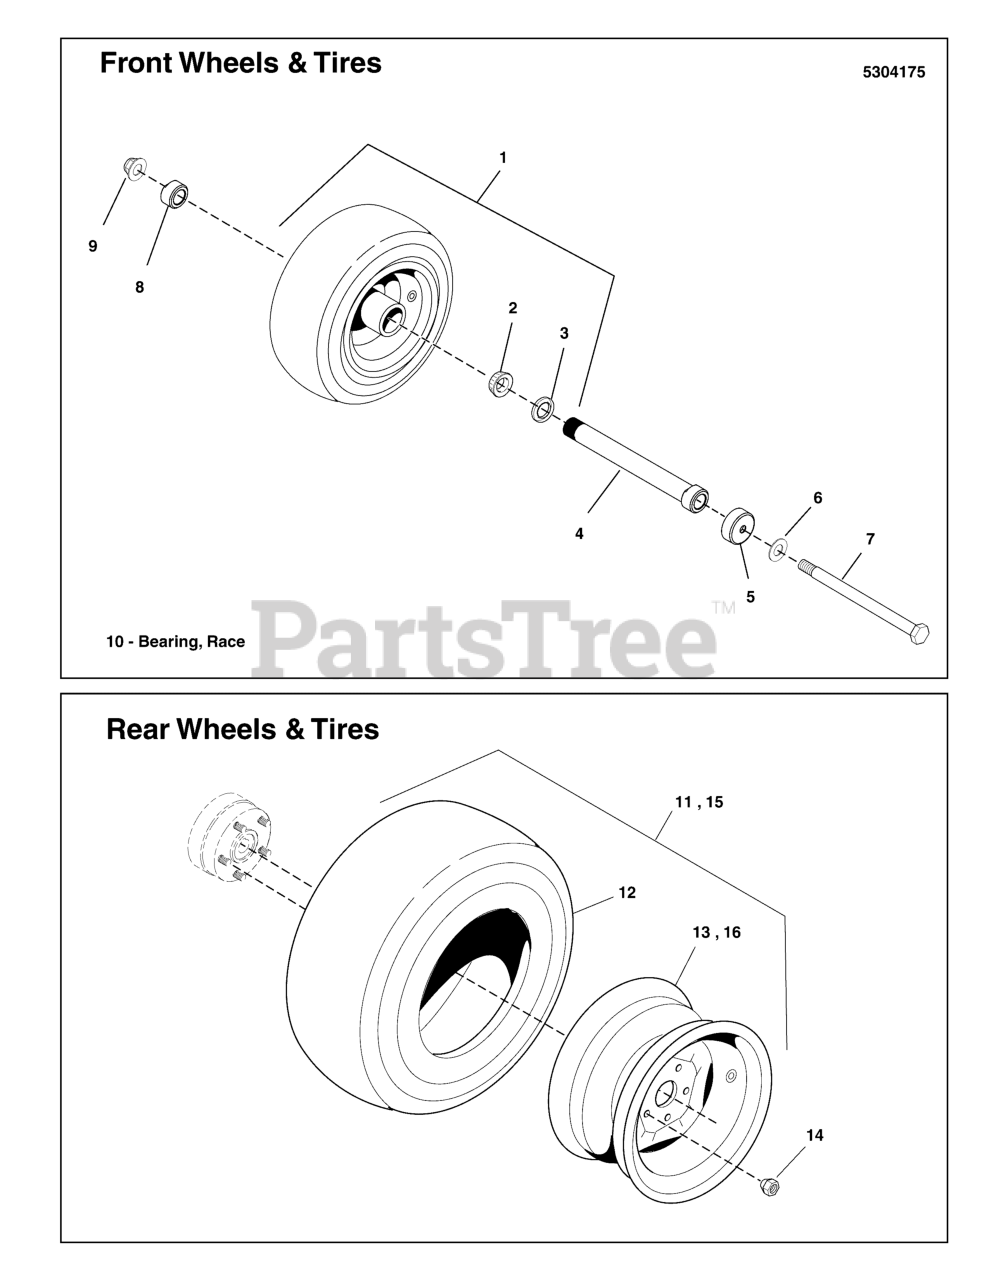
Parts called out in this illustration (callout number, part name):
1	TIRE ASSM, 13 X 5 - 6, FF / TB
2	BEARING, Tapered Roller
3	SEAL, GREASE
4	BEARING ADJUSTER, SPACER, 6.062 LG
5	DEBRIS, COVER, CASTER WHEELS
6	WASHER, 1/2 SAE
7	BOLT, 1/2-13 X 8 GD5 CZ
8	NUT, BEARING ADJUSTER, AXLE
9	NUT, Hex Flange, Nylock, 1/2-13
10	BEARING, RACE
11	TIRE WHEEL ASM, 23X10.5-12, TURF SMART
11	TIRE WHEEL ASM, 23X10.50-12, TURF MASTER
12	TIRE, 23 X 10.5-12NHS, TURF SMART
12	TIRE
13	WHEEL, 12 X 8.5, 5/4.5
14	NUT, 1/2-20, FOR WHEEL BOLT SILVER
15	TIRE ASSM, 23 X 10.5-12, TURF SMART
15	TIRE WHEEL ASM, 23X10.50-12, TURF MASTER
16	WHEEL, 12 X 8.5, 5/4.5, 1.3 OFFSET
